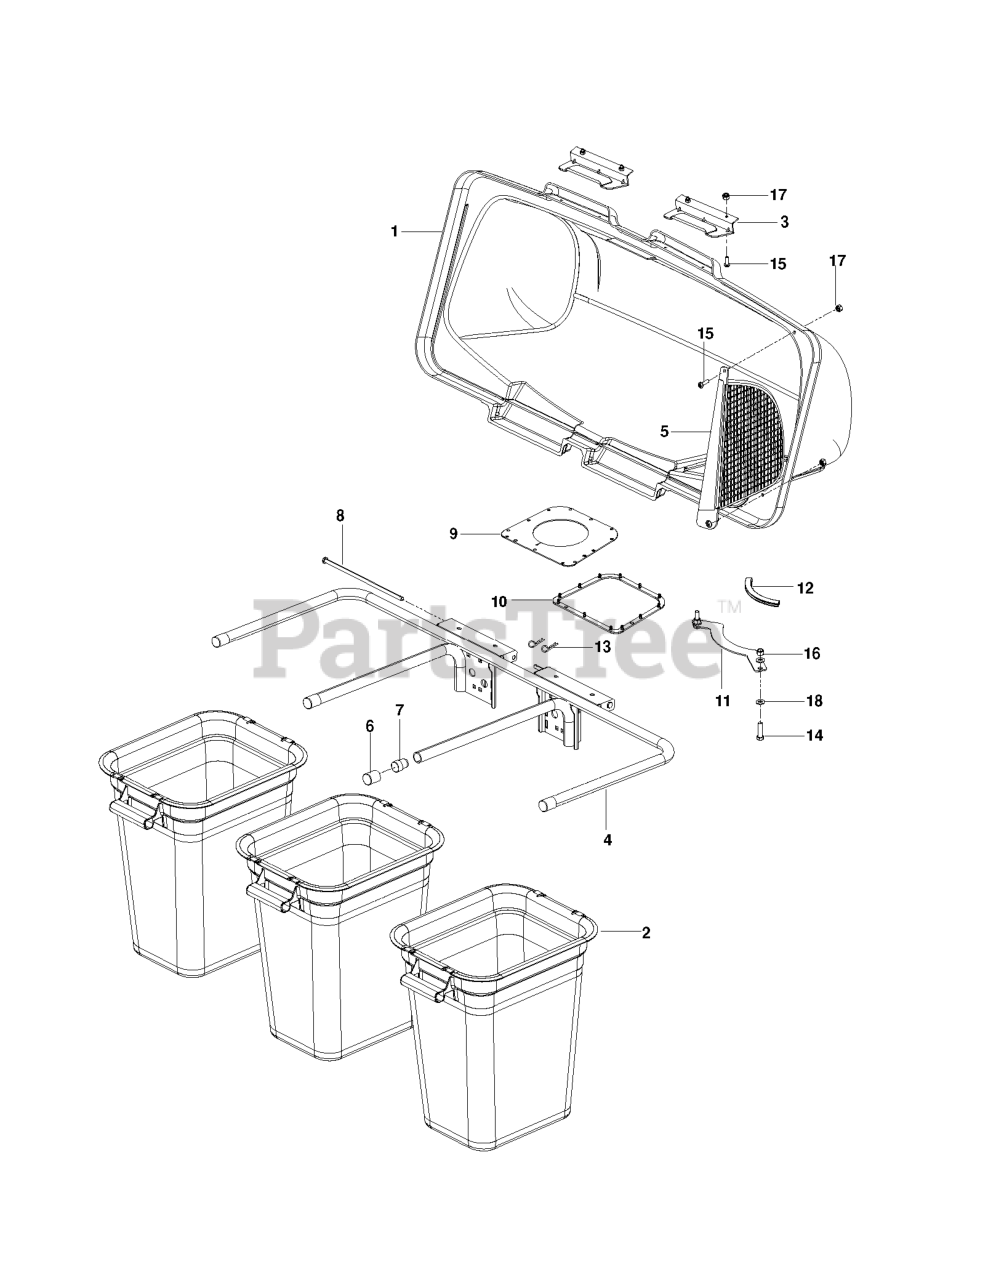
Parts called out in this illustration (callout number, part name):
1	COVER.ASM.3BIN.GENERIC.
2	CONTAINER BAG, SOFT
3	LATCH CER38
4	BAGGER, FRAME
5	SCREEN.COVER.BAGGER
6	TUBING PLUG
7	SPACER PLUG, BAGGER
8	BAGGER.HINGE.PIN
9	SEAL.BAGGER.TOP.3-BIN.BLK
10	GASKET.COVER.BAGGER
11	SUPPORT.CHUTE.COLLECTION.BLACK
12	RP.FLEX TRIM, BLK-LENGTH 1 FT
13	RETAINER SPRING
14	HCS 5/16C X 1 1/4
15	SCREW #10-24 X 5/8
16	5/16-18 NYLOC FLANGE NUT
17	NUT 10-24 NYLOC
18	FLAT WASHER 5/16 SAE
